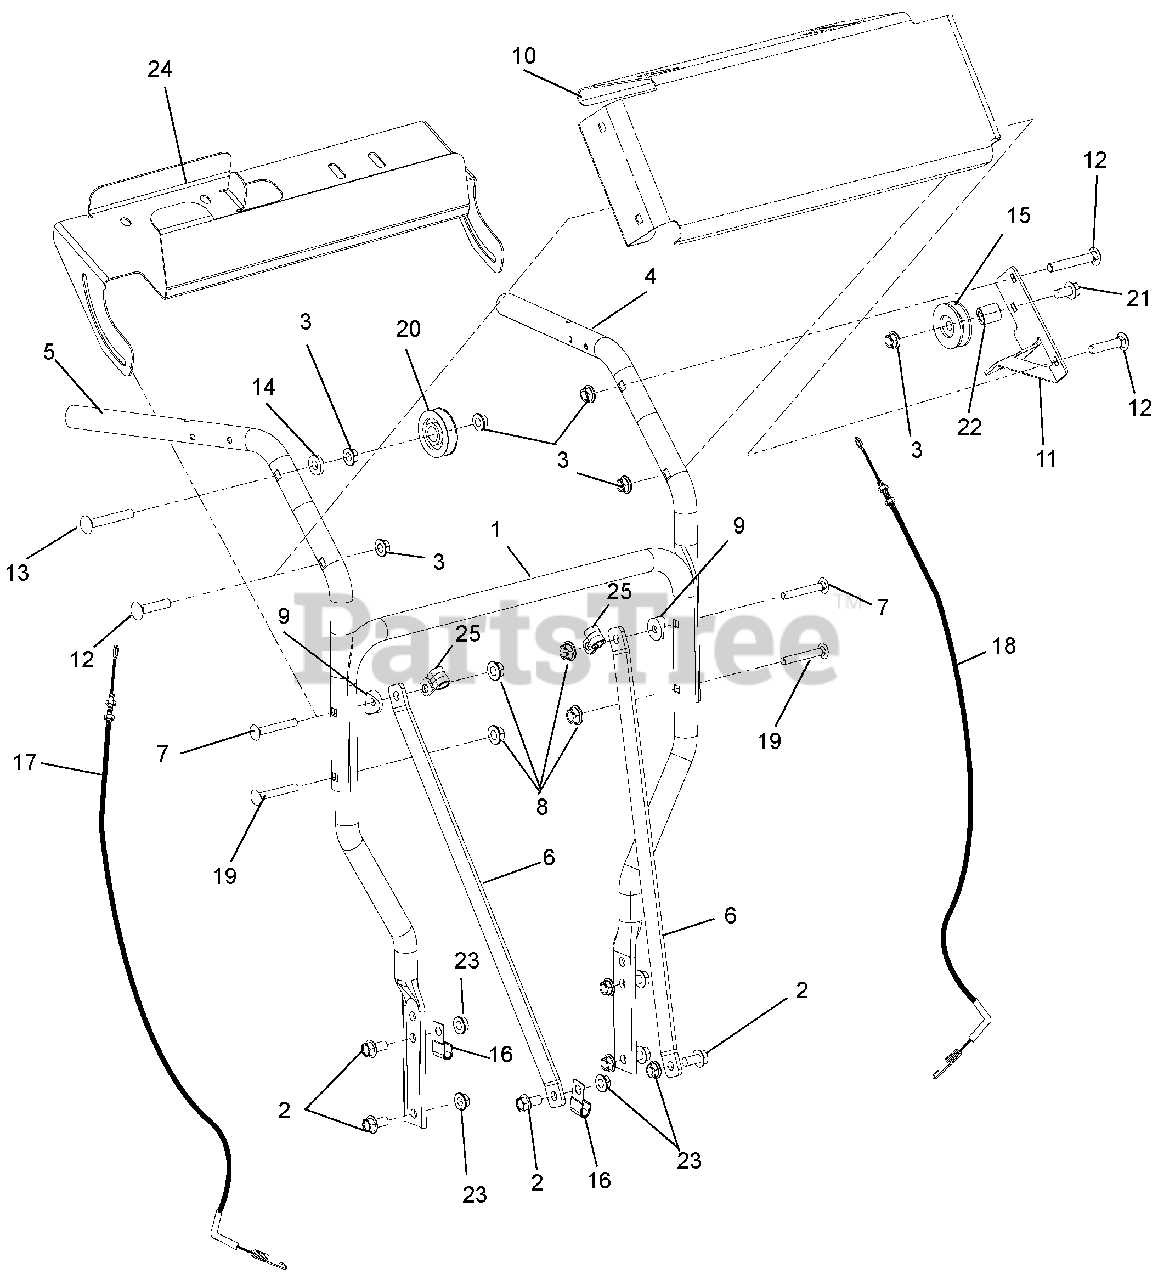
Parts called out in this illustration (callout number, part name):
1	HANDLEBAR, LOWER
2	BLT-SERHFWH .38-16X.75 YWZC
3	@NUT-LK-TOP-FLG .38-16 YWZC
4	WMT-HANDLEBAR, UPPER LH
5	HANDLEBAR, UPPER RH
6	BRKT-BRACE, HANDLEBARS
7	@BLT-RDHDSQNK .31-18X2.25 G5YZ
8	@NUT-LK-NYL-FLG .31-18 YWZC
9	SPACER, HANDLEBAR
10	DASH, WAW
11	MOUNT, WAW PTO CABLE (WLDMNT)
12	@BLT-RDHDSQNK .38-16X1.75 G5YZ
13	@BLT-RDHDSQNK .38-16X2.50 G5YZ
14	WSHR-FL-STL .406X1.00X.188 YWZ
15	IDLER, 3L FRONT SIDE .38X1.875
16	J-CLAMP
17	CABLE, WAW P-BRAKE
18	CABLE, WAW PTO
19	@BLT-RDHDSQNK .31-18X1.75 G5YZ
20	PULLEY, CABLE
21	@BLT-HEX .38-16X2.50 GR5 YWZC
22	SPACER, .437X1.0X1.23
23	NUT-LK-CTR-FLG .38-16 YWZC
24	BRKT, EMISSION COMPONENT MOUNT
25	CLAMP, CUSHIONED STEEL
